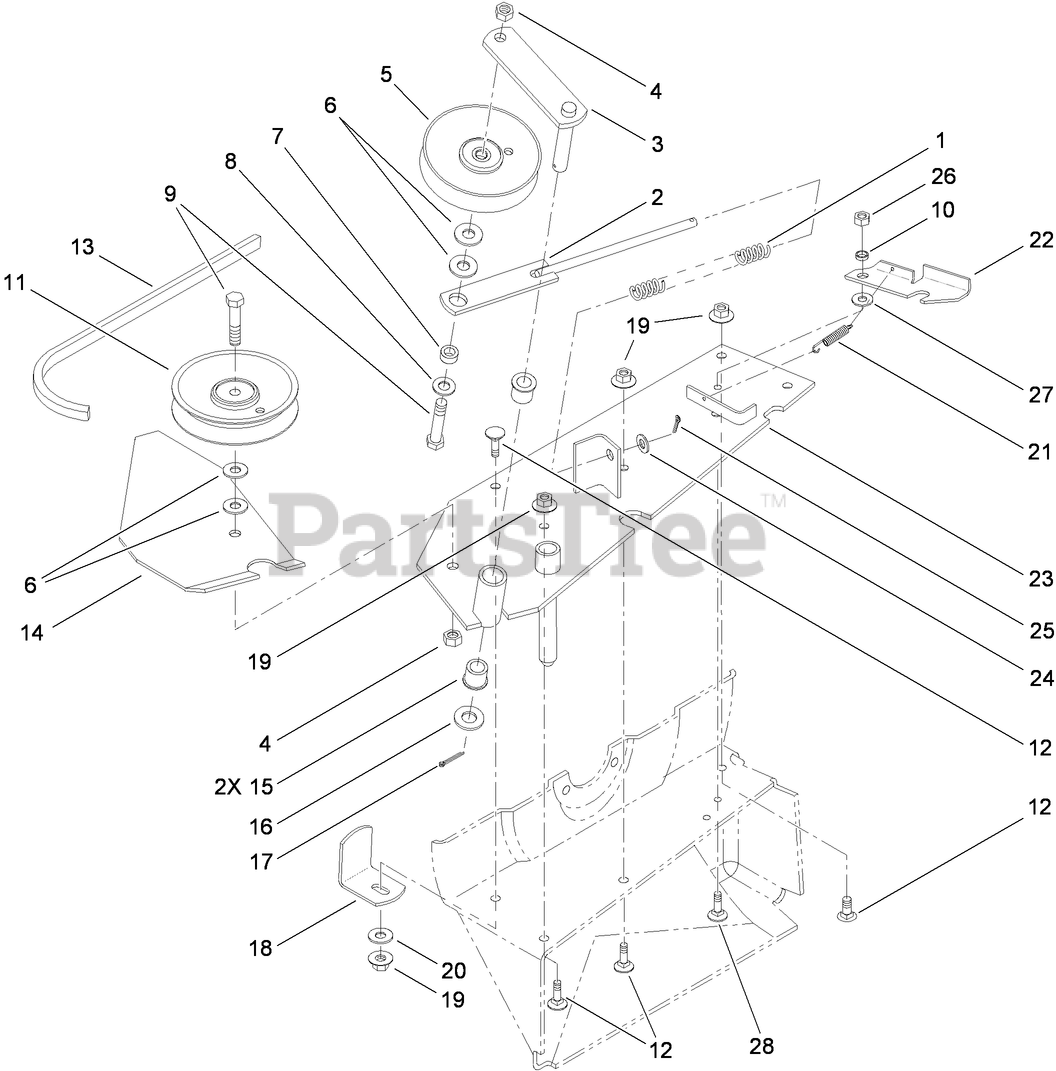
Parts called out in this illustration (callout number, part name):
1	SPRING-COMPRESSION
2	SPRING-ROD
3	IDLER ARM ASM
4	NUT-LOCK, NI
5	PULLEY-IDLER
6	WASHER-FLAT
7	SPACER
8	WASHER-FLAT
9	SCREW-HH
10	BUSHING
11	PULLEY-IDLER
12	SCREW-CARR
13	BELT-V
14	SUPPORT-SHIELD, BELT
15	BUSHING
16	WASHER-FLAT
17	PIN-COTTER
18	BRACKET-SUPPORT, HOUSING
19	NUT-HF
20	WASHER-FLAT
21	SPRING-EXTENSION
22	LATCH-BLOWER
23	MOUNTING-BLOWER
24	WASHER-PLAIN
25	PIN-COTTER
26	NUT-LOCK, NI
27	WASHER-FLAT
28	BOLT-CARR
